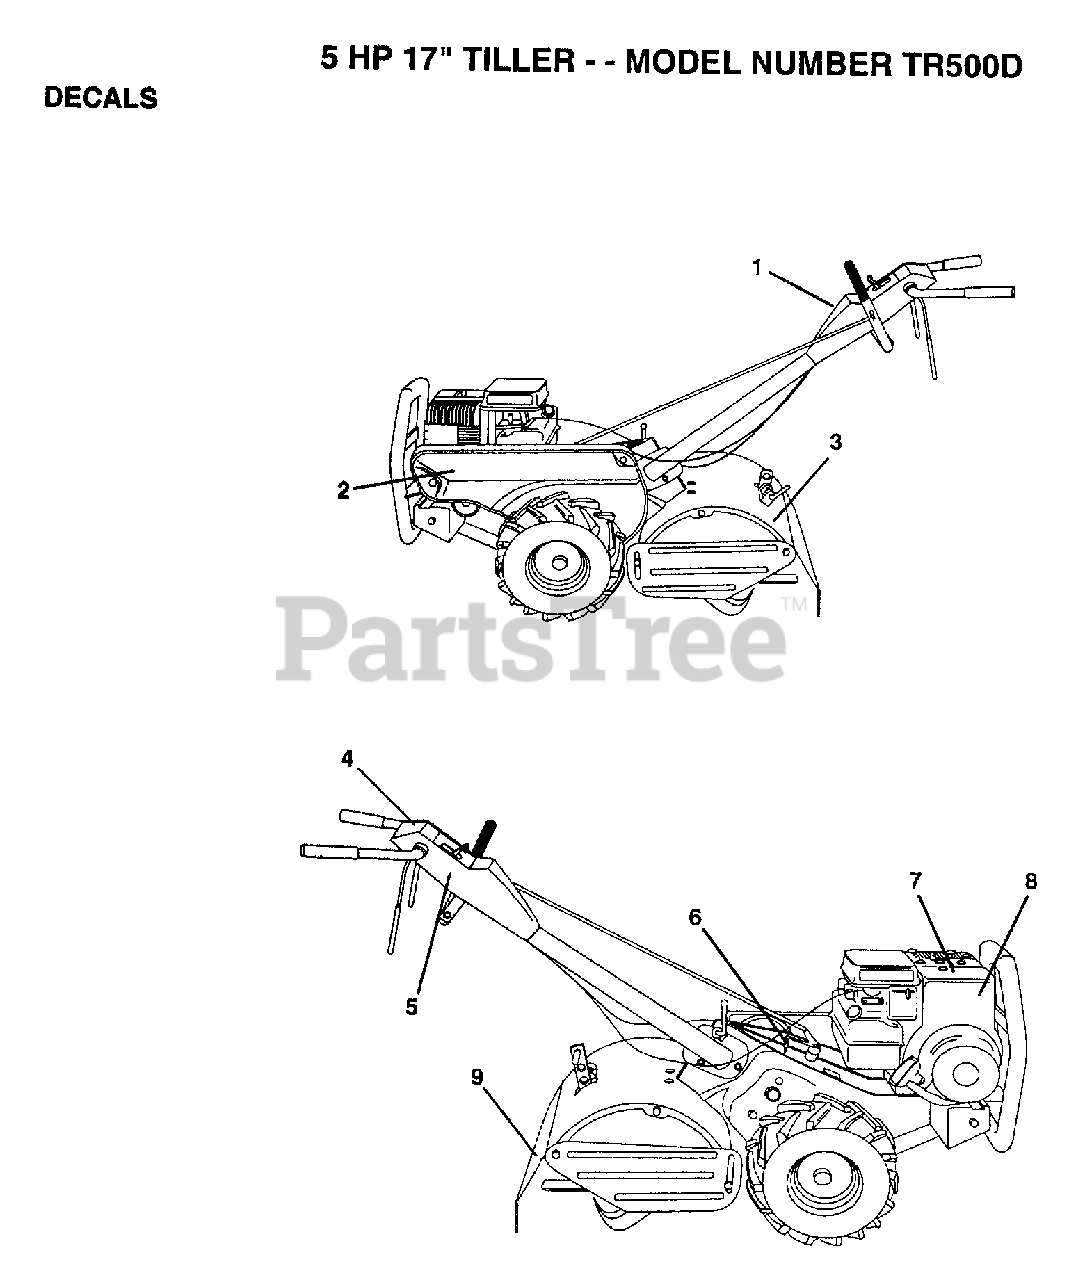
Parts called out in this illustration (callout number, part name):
1	DECAL.PNL.CONTROL
3	DECAL.SHLD.TINE
4	DECAL.INSTRUCTION
5	DECAL TI
6	DECAL CRT
9	DECAL TI
